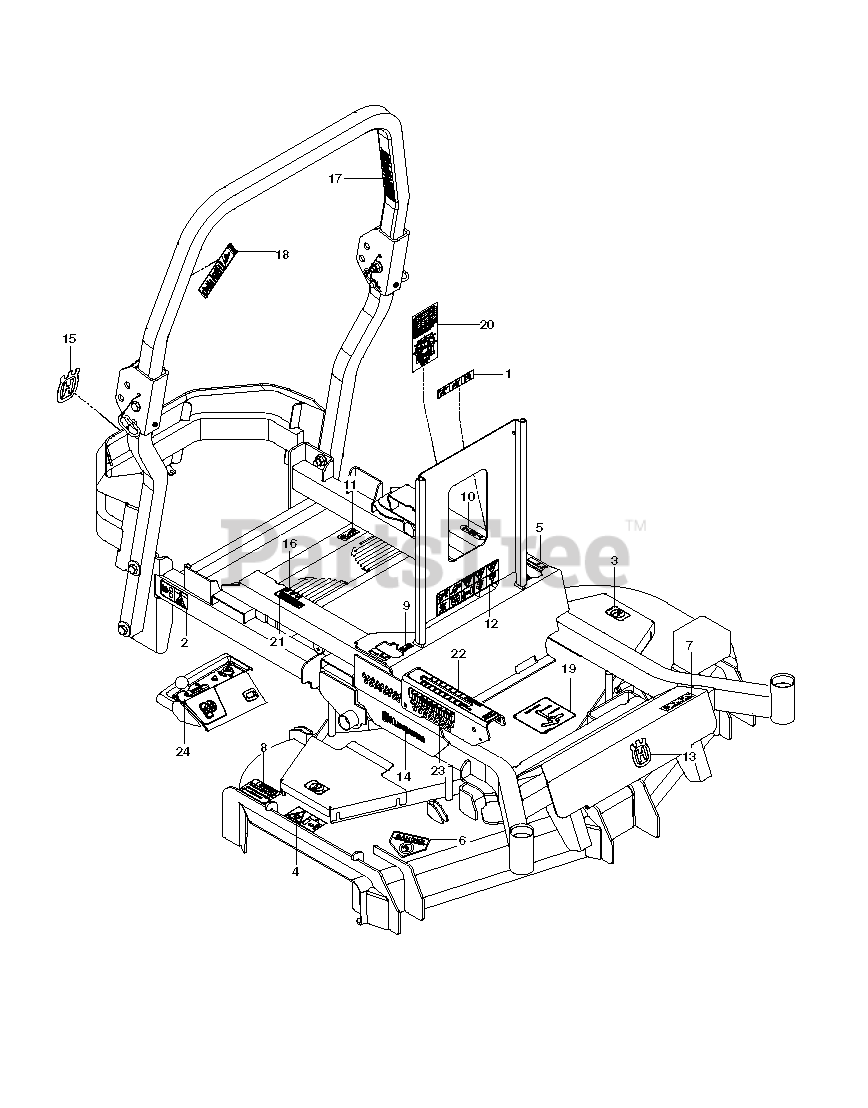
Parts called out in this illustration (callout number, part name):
1	EURO DECAL-BATTERY WARNIN6
2	DECAL, BELT DRIVE
3	DECAL.DECK.6MIL.EURO.NOSTEP
4	DECAL, EURO SEVERING
5	DECAL, MOTION CONTROL
6	DECAL, CPSC
7	DECAL.ZTRPZ54.HUSQVARNA
8	DECAL.DECK.6MIL./DEF.SHLD.WARN
9	DECAL, F.S.T.
10	DECAL, PARK BRAKE
11	DECAL, FUEL
12	DECAL, WARNING
13	DECAL.AUGER.HUSQ.CROWN.SNOW
14	RP.DECAL.BADGE.170MM.TEXTLOGO
15	DECAL, CROWN H, 110MM
16	DECAL, FUSE
17	DECAL, ROPS
18	DECAL, ROPS, WARNING
19	DECAL, BELT ROUTING
20	DECAL, SERVICE
21	DECAL, WARNING SPARK ARRESTOR
22	DECAL, HEIGHT
23	DECAL, HEIGHT
24	DECAL.CONTROLPANEL.CHECKENGINE
